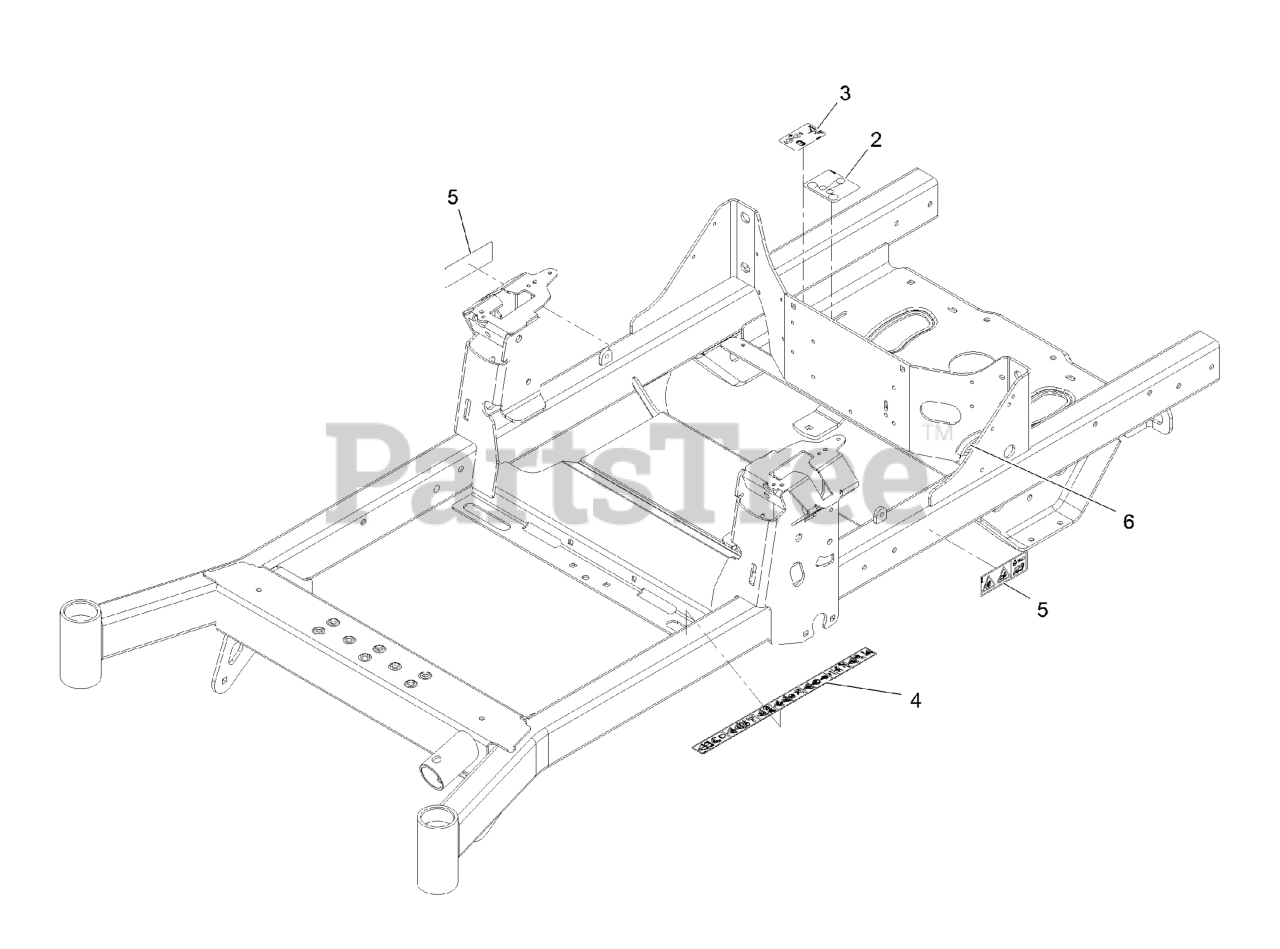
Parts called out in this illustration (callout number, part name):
2	DECAL-ROUTING, BELT
3	DECAL-RELEASE, DRIVE
4	DECAL-WARNING(AURORA)
5	DECAL-WARNING
6	STRIP-SEAL
